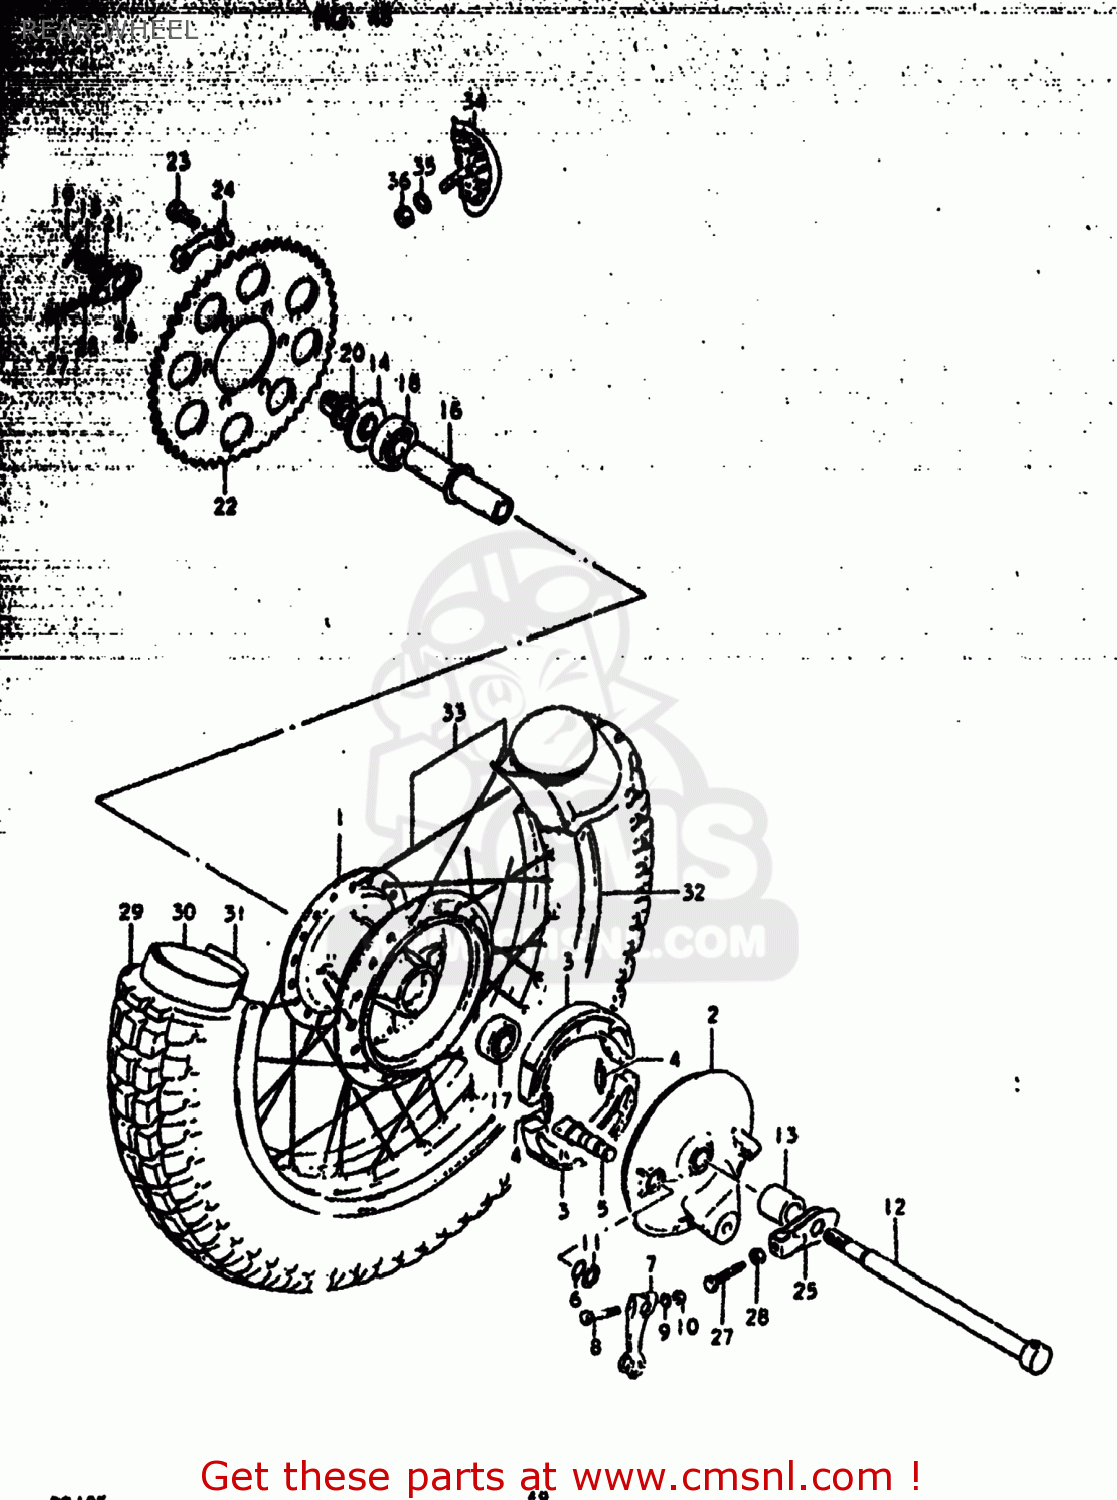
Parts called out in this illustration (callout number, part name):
1	HUB,REAR WHEEL
2	PANEL,REAR HUB
3	SHOE,BRAKE
4	SPRING(L:34)
5	CAM,FR BRAKE
6	O RING(D:2.5,ID:11.4)
7	LEVER,REAR BRAKE CAM
8	BOLT
9	WASHER
10	NUT
11	WASHER(12.5X20X1)
12	AXLE,REAR
13	SPACER(15.2X22X26)
14	SPACER,RR AXLE,L
15	NUT 12MM
16	SPACER,RR WHEEL HUB BEARING
17	BEARING
18	BEARING
19	COTTER PIN
20	SPACER,CHAIN ADJUSTER,L
21	NUT
22	SPROCKET,REAR
23	BOLT(8X30)
24	WASHER
25	ADJUSTER,CHAIN,R
26	ADJUSTER,CHAIN,L
27	BOLT
28	NUT
29	TIRE
30	TUBE ASSEMBLY,WHEEL,INNER
31	PROTECTOR,INNER TUBE
32	RIM,REAR WHEEL
33	SPOKE SET
34	STOPPER,BEAD
35	WASHER
36	NUT
